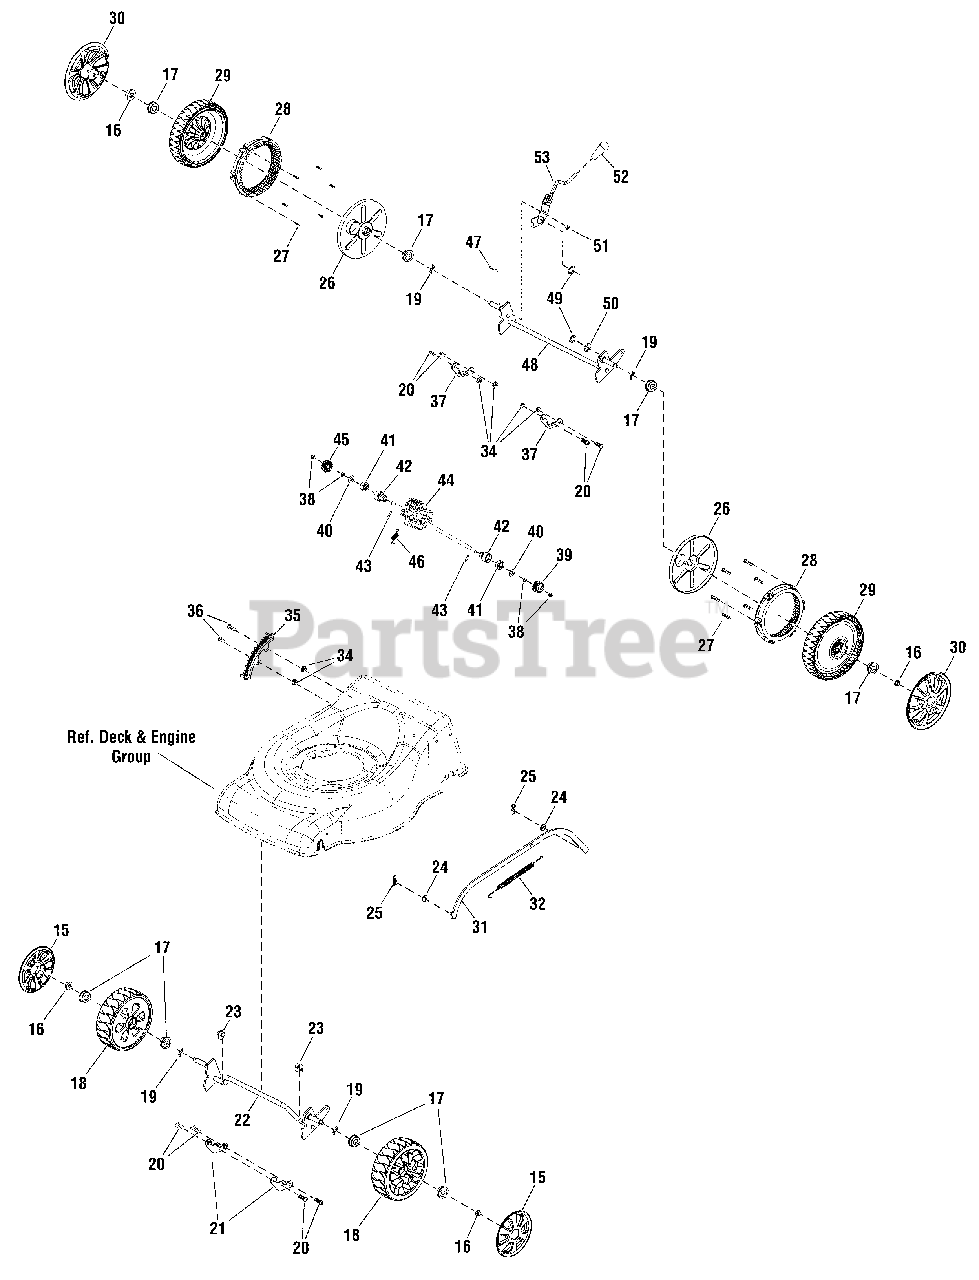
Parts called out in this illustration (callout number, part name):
15	HUBCAP, Front
16	* NUT, Hex Lock
17	BEARING
18	WHEEL ASSEMBLY, Front
19	WASHER, Wave
20	* SCREW
21	BRACKET, Wheel Axle
22	AXLE ASSEMBLY, Front
23	CLAMP, Axle, Front
24	* WASHER, Flat
26	DUST COVER
28	GEAR, Wheel
29	WHEEL ASSEMBLY, Rear
30	HUBCAP, Rear
31	CONNECTING LINK
34	* NUT, Hex Lock
35	BRACKET, Height Adjustment
36	* SCREW
37	BRACKET, Wheel Axle
38	WASHER, Split
39	GEAR, LH
40	* WASHER, Flat
41	BEARING
42	HOLDER, Bearing
44	GEARBOX ASSEMBLY
45	GEAR, RH
47	SCREW, Pan Head
48	AXLE ASSEMBLY, Rear
49	WASHER, Split
50	WASHER, Adjustment
51	* NUT, Hex Lock
53	LEVER, Handle
